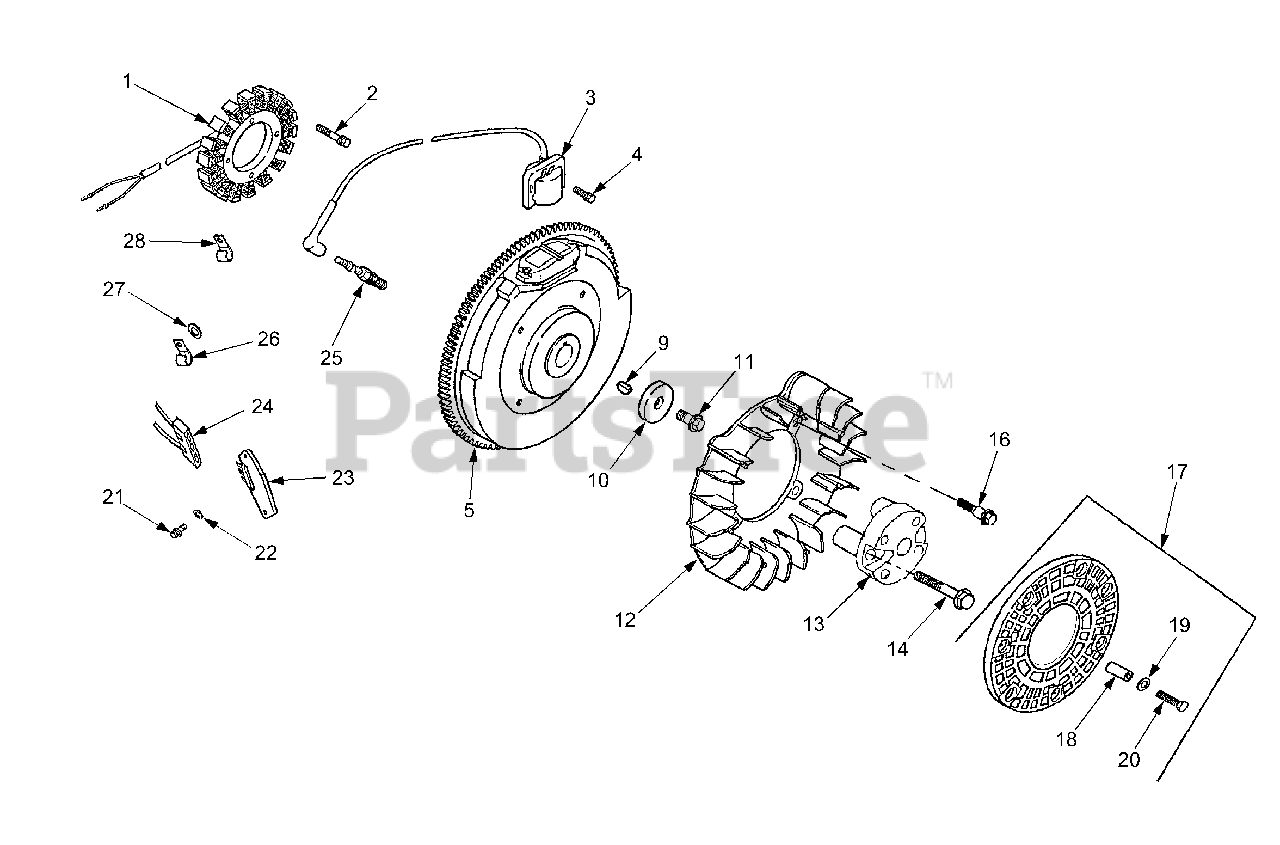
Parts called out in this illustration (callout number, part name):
1	Kit, 15 Amp Stator
2	Screw, Hex Cap M5 x 0.8 x 25
3	Module, Ignition
4	Screw, Hex Socket Hd. M5 x 0.8 x
5	Flywheel
10	Washer, Plain 3/8"
11	Screw, Hex Flange M10 x 1.5 x 46
12	Fan
13	Adapter, Drive Shaft
14	Screw, Hex Flange M10 x 1.5 x 90
16	Bolt, Shoulder, M6 x 1.0 x 16
17	Kit,Grass Screen
19	Washer, Plain 3/16"
20	Screw, Hex Cap M4 x 0.7 x 25
21	Screw, Phillips Hd. 11-16 x 7/8"
22	Washer, Plain 3/16"
23	Rectifier-regulator 15 Amp
24	Connector (3 Contact)
25	Spark Plug
26	Clip, Cable
27	Washer, Plain 1/4"
